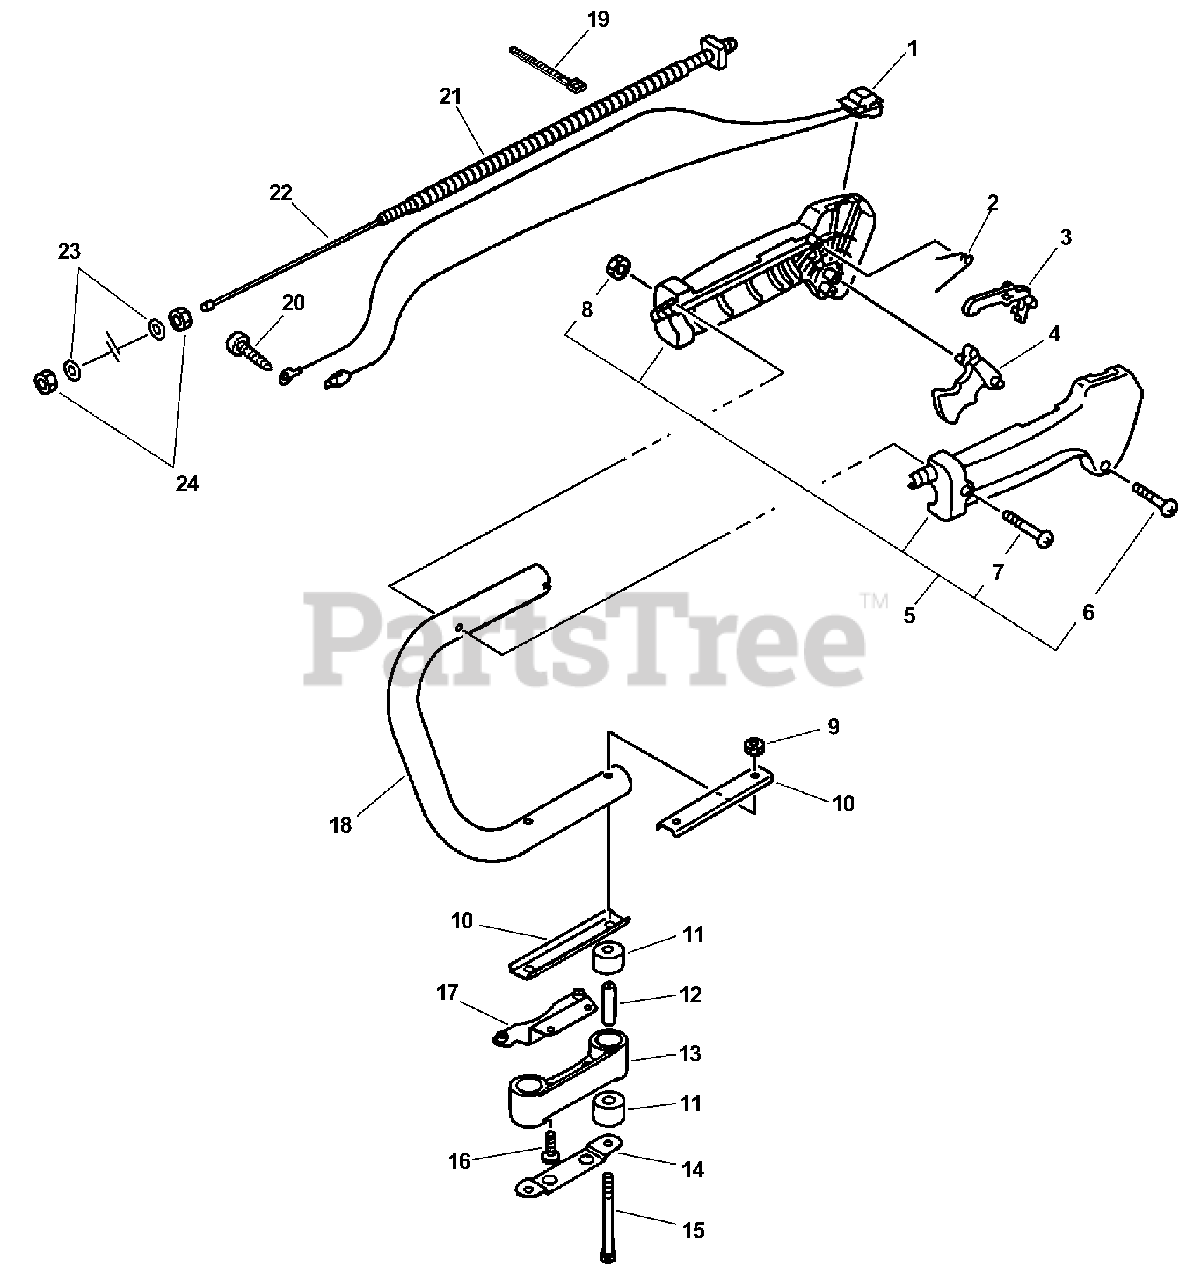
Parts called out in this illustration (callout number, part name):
1	IGNITION SWITCH ASSY
2	SPRING, LOCKOUT LEVER
3	LOCKOUT, THROTTLE
4	TRIGGER, THROTTLE
5	THROTTLE CONTROL ASSY
6	SCREW - 3X25
7	SCREW - 5X30
9	LOCKNUT - 5
10	BRACKET, HANDLE - LOWER
12	SPACER
13	BRACKET, HANDLE
14	PLATE, CUSHION
15	SCREW - 5X60
16	SCREW - 5X16
18	HANDLE - REAR
19	TIE, CABLE
20	SCREW - 5X10
22	CABLE, THROTTLE
23	WASHER - 6
